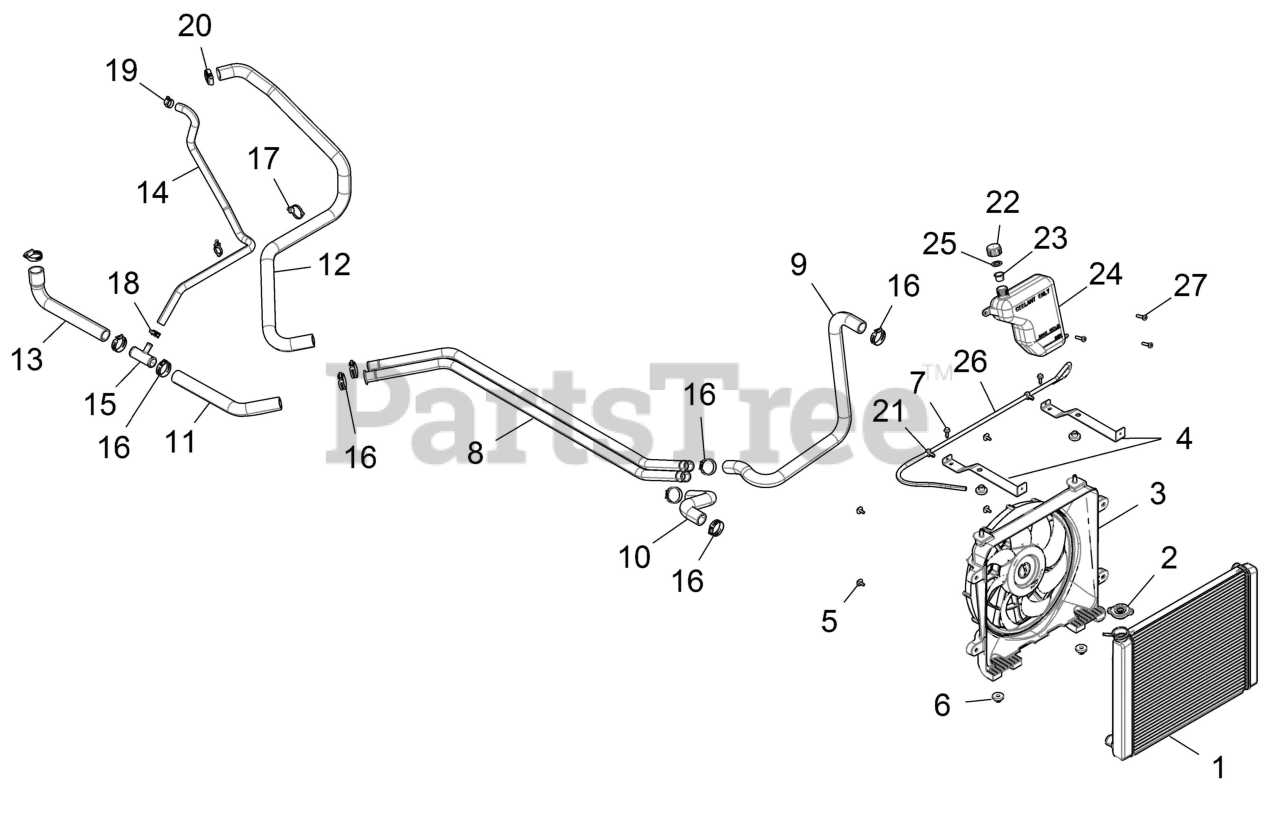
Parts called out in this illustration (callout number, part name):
1	ASM-RADIATOR,CORE
3	FAN-ASSEMBLY
4	MOUNT, RADIATOR, BLACK
5	BOLT-M6X15MM
7	SCR-M6X1.0X20,HXHD,FLG,TDFM,BL
8	TUBE, COOLANT, 1 IN
9	HOSE-UPPER,RAD
10	HOSE-LOWER,RAD
11	HOSE-ENG,IN
12	HOSE-ENG,OUT
13	HOSE-ENG,INLET/BYPASS
14	HOSE-BYPASS
15	CONNECTOR-TEE,1X1X0.5
16	CLAMP,SPRINGBAND 35/12,BLK
17	CLIP-ROUTING
18	CLAMP-HOSE,SPRING,20MM
19	CLAMP, HOSE (10)
20	CLAMP-HOSE(WORM DR)25-40MM
22	CAP, OVERFLOW
23	CAP,PLUG9X(GRN),FLEX TEMP(10)
24	TANK-SURGE
25	GASKET (10)
26	FUEL LINE-95 CENTIMETERS
27	SCR-#14X1 HI/LO-PH-PN TRX-M
